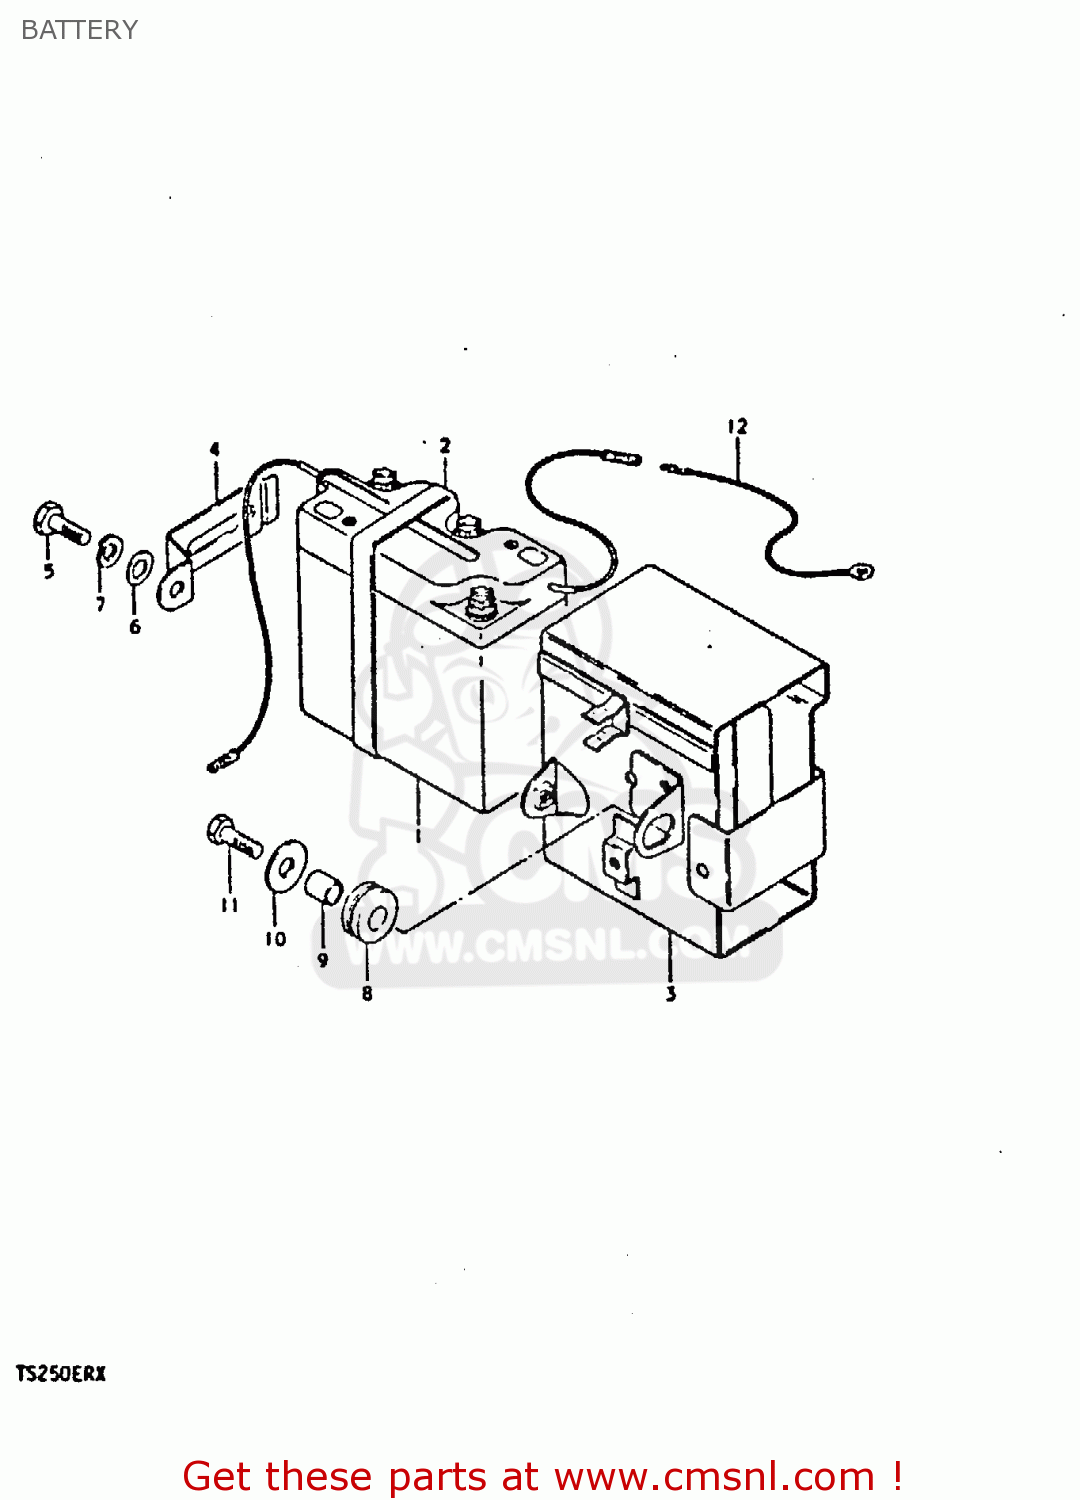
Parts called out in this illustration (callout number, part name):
1	BATTERY(6N4B-2A,6V4.2AH)
2	PROTECTOR,BATTERY
3	HOLDER,BATTERY
4	PLATE,BATTERY HOLDER
5	SCREW(6X10)
6	WASHER
7	LOCK WASHER
8	CUSHION
9	SPACER (7X9X7)
10	WASHER (6.5X20X1.2)
11	SCREW
12	LEAD WIRE
